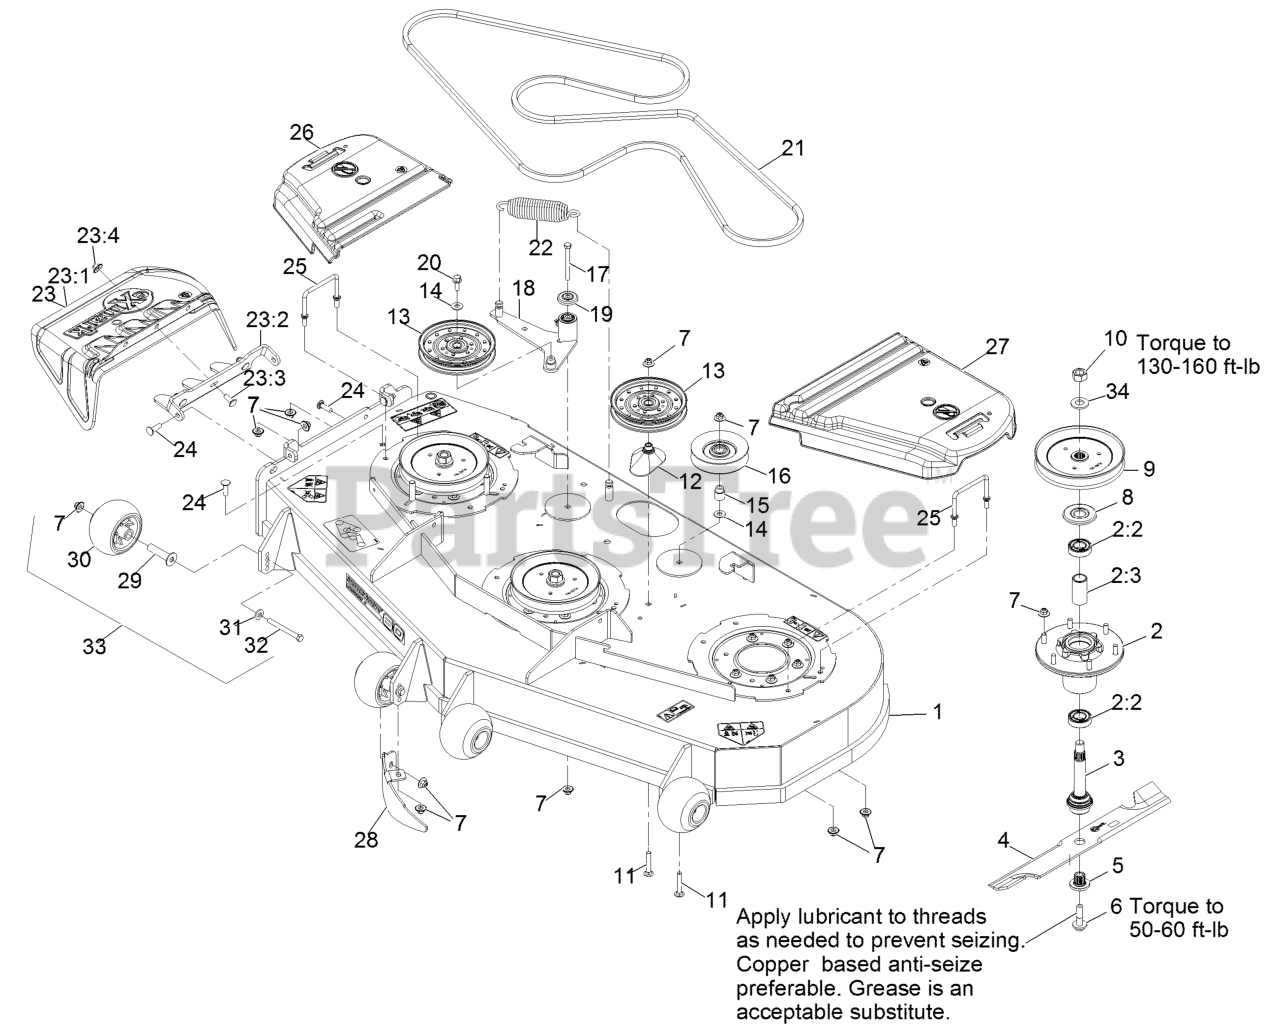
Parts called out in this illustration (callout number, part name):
1	DECK ASM-604
2	ASM-CUTTER HSG WITH BEARINGS
2:2	BEARING-BALL
2:3	SPACER-BEARING
3	ASM-SPINDLE AND SEAL
4	Blade-Extreme 2, 20.50"
5	BUSHING,SPLINED
6	SCREW,SEMS 1/2-20 X 2.19
7	Nut-Nyloc 3/8-16 Flg
8	GUARD,BEARING TOP .989
9	SHEAVE,BLADE DRIVE 7.25
10	NUT-HEX
11	Bolt-Carriage 3/8-16 X 2 1/4
12	SPACER-PULLEY
13	IDLER-PULLEY
14	WASHER-FLAT
15	BUSHING-IDLER
16	PULLEY-IDLER
17	SCREW-HH
18	DECK IDLER ASM
19	GUARD-TOP
20	SCREW-HHF
21	V-BELT
22	SPRING-EXTENSION
23	ASM,DISCHARGE CHUTE
23:1	CHUTE,DISCHARGE
23:2	BRACKET,DISCHARGE CHUTE
23:3	SCREW-CARR
23:4	Nut-Nyloc 3/8-16 Flg
24	Bolt-Carriage 3/8-16 X 1 1/4
25	WIREFORM-COVER
26	COVER-BELT, RH
27	COVER-BELT, LH
28	DOGLEG - LZ60
29	AXLE, ROLLER
30	ROLLER-SCALP, ANTI
31	WASHER-BELLEVILLE
32	SCREW-HH 3/8-16 X 3 3/4 GR 8
33	KIT, ANTI-SCALP ROLLER
35	SHIELD-DUST
36	SCREW-CARR
